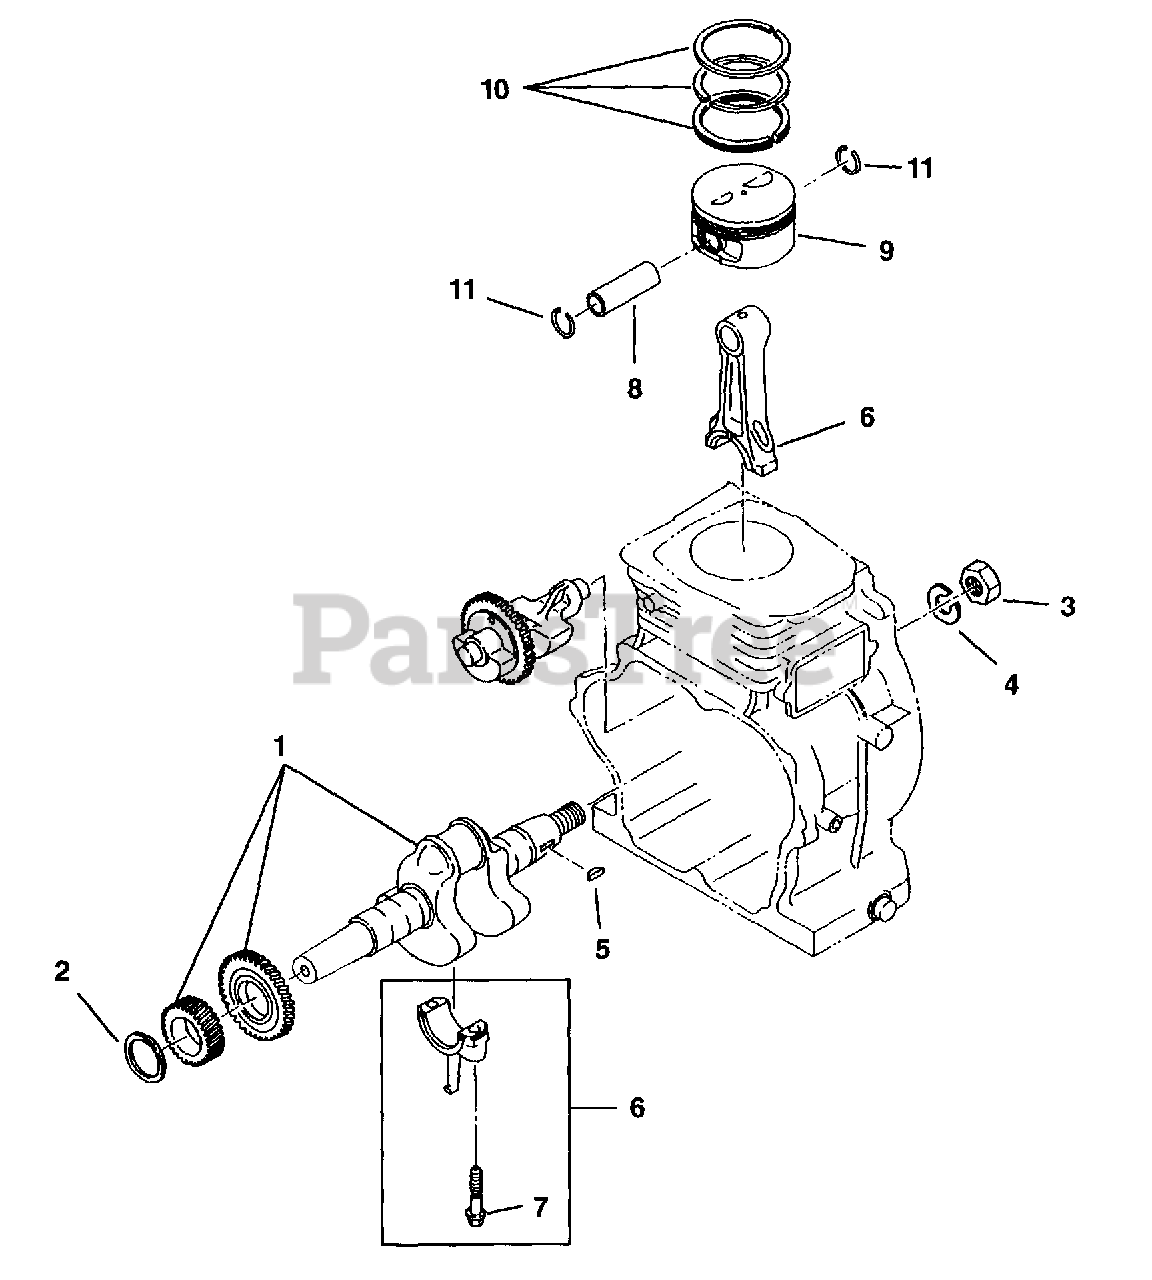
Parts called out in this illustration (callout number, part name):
1	Crankshaft
2	Spacer (.6)
3	Nut
4	Spring washer
5	Woodruff key
6	Connecting rod
7	Connecting rod bolt M8 x 46
8	Piston pin
9	Piston (std)
10	Piston ring set (std)
